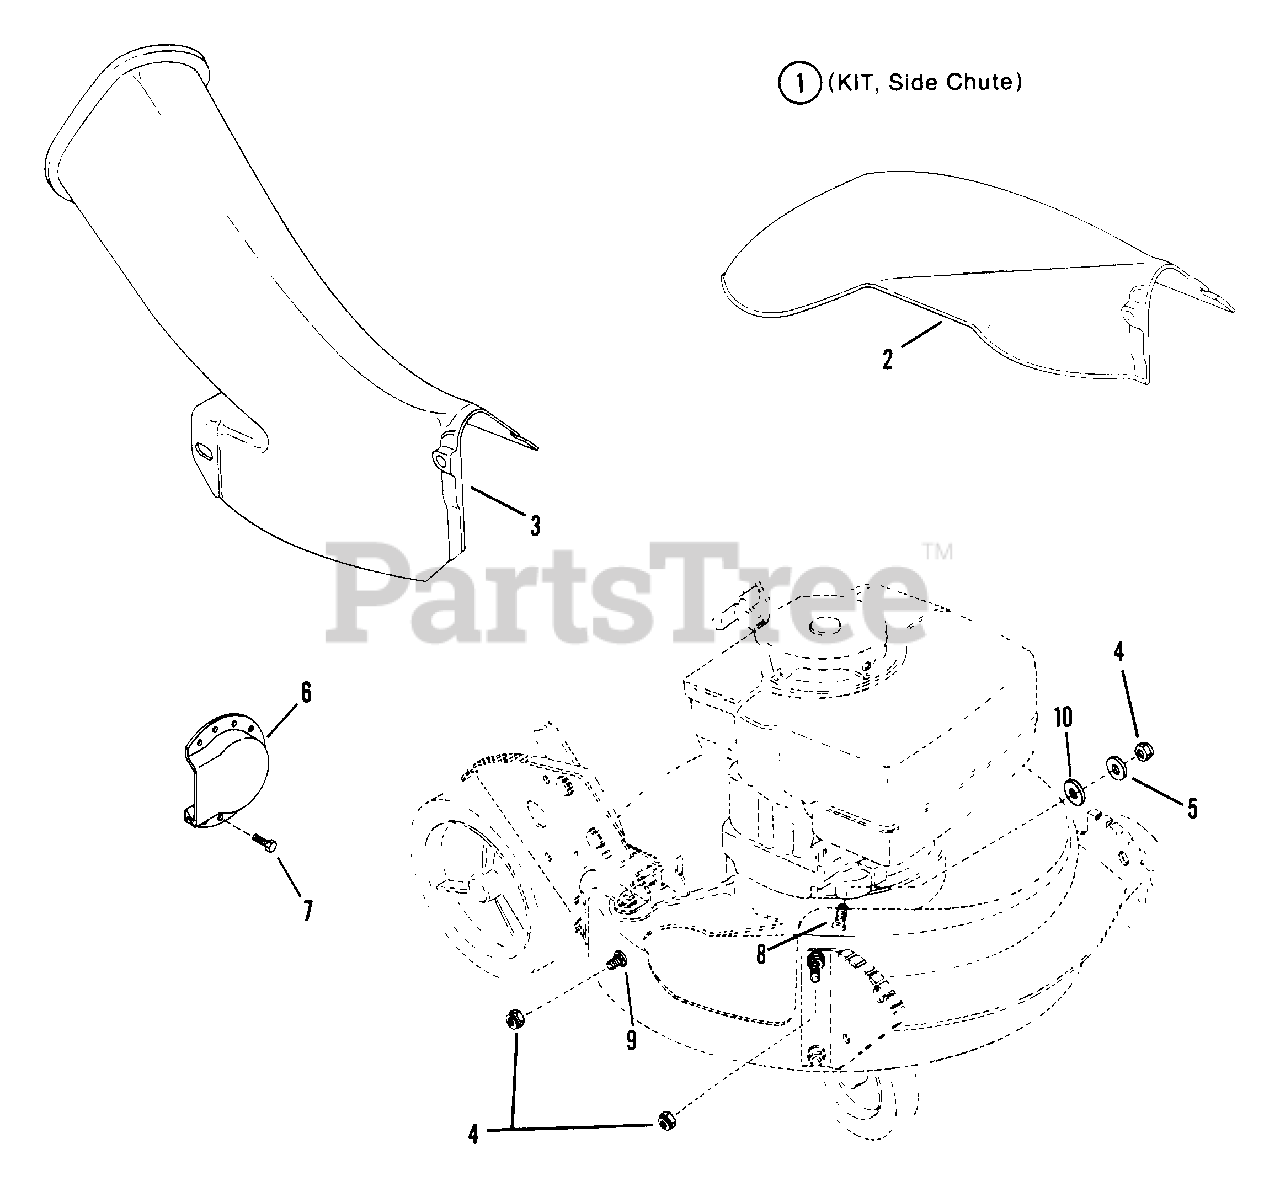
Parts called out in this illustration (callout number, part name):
1	KIT, Side Chute
2	CHUTE, Side
3	ADAPTER, Grass Bag Deck
4	NUT,5/16-18 Hex Lock Flange Lock
5	WASHER, 5/16 Flat
6	DEFLECTOR, Muffler
7	SCREW, #8-18 x 3/8" Hex Head Cap
8	BOLT, 5/16-18 x 3/4" Carriage
9	RETAINER, 5/16 Bolt
10	WASHER, 5/16 Flat
